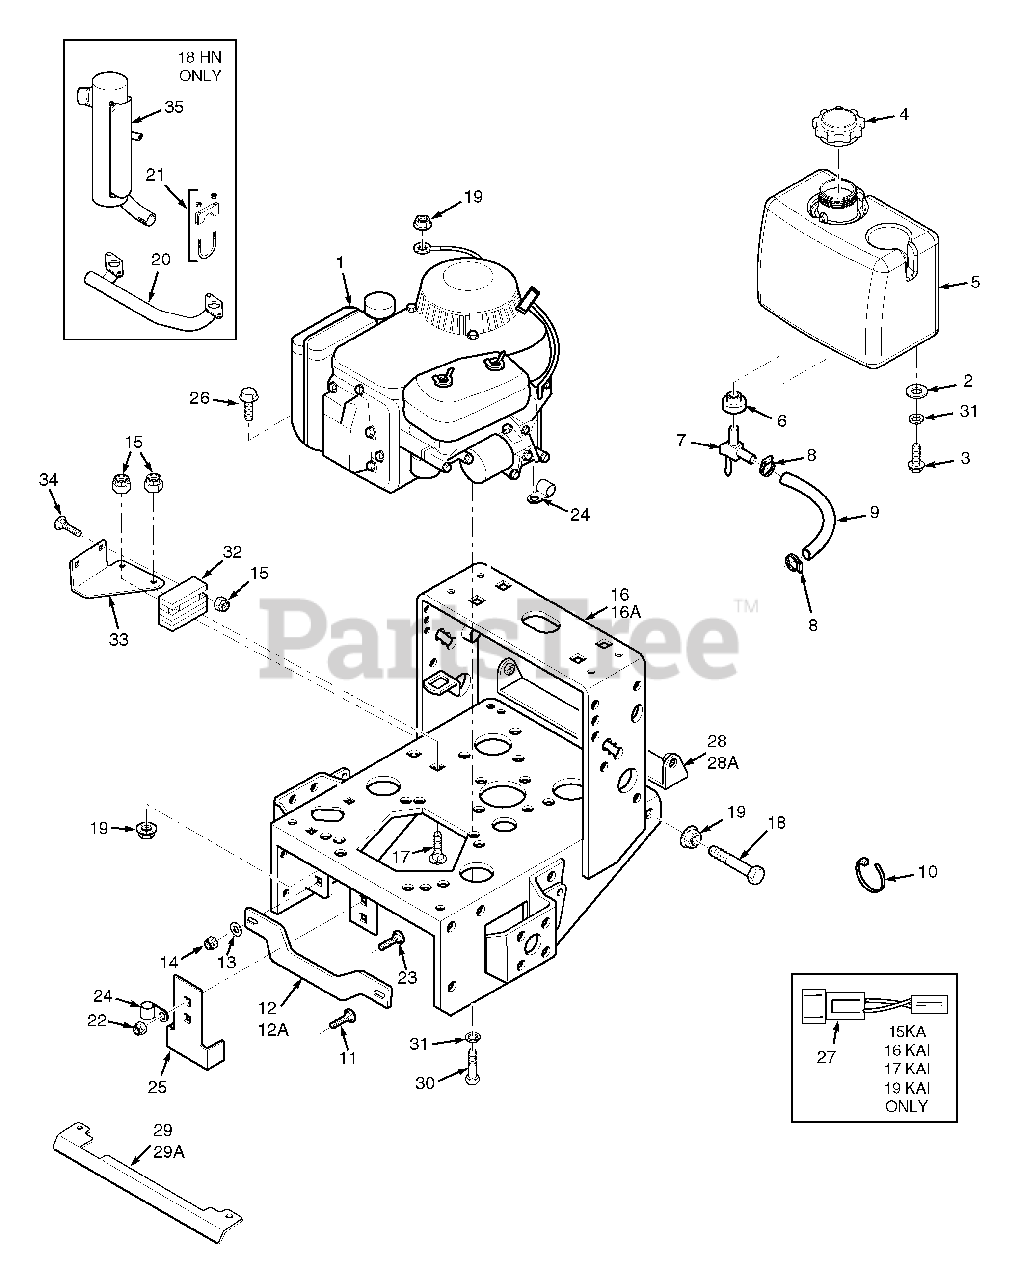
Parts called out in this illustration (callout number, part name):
1	Engine, 17KAI Kawasaki
2	Flatwasher, 5/16 (.375 x .875 x .083)
3	Capscrew, 5/16-18 x 1" Hex Head
4	Cap, Fuel Tank
5	Fuel Tank Assy.
6	Bushing
7	Valve, Fuel Shut-off
8	Clamp, Fuel Hose
9	Fuel Hose, 1/4 ID x 18"
10	Cable Tie
11	Carriage Bolt, 3/8-16 X 1-1/4"
12	Brace, (16" Small Frame)
12A	Brace, (20" Large Frame)
13	Flat Washer .391 x .938 x .105
14	Nut, 3/8-16 Elastic Stop
15	Nut, 1/4-20 Elastic Stop
16	Engine Deck, 16" Wide, w/decals
16A	Engine Deck, 20" Wide, w/decals
17	Bolt, 1/4-20 x 1-1/4" Carriage
18	Bolt, 5/16-18 x 2" Hex Head
19	Nut, 5/16-18 Serr. Flange
20	Manifold, Exhaust
21	Clamp, Muffler
22	Nut, 5/16-18 Elastic Stop
23	Carriage Bolt, 5/16-18 x 1"
25	Clutch Bracket
26	Cap Scrw, 5/16-18 x 1.50" Sr. Flg
27	Wire Hrns. Adapter, 15KA, 16KAI, 17KAI & 19 KAI
28	Pulley Guard, 16" Frame
28A	Pulley Guard, 20" Frame
29	Heatshield (16" Small Frame)
29A	Heatshield (20" Large Frame)
30	Bolt, 5/16-18 x 1" Serrated Flange Hex Head
31	Lock Washer 5/16"
32	Rectifier
33	Mounting Bracket, Rectifier
34	Bolt, 1/4-20 x 1" Carriage
35	Muffler
